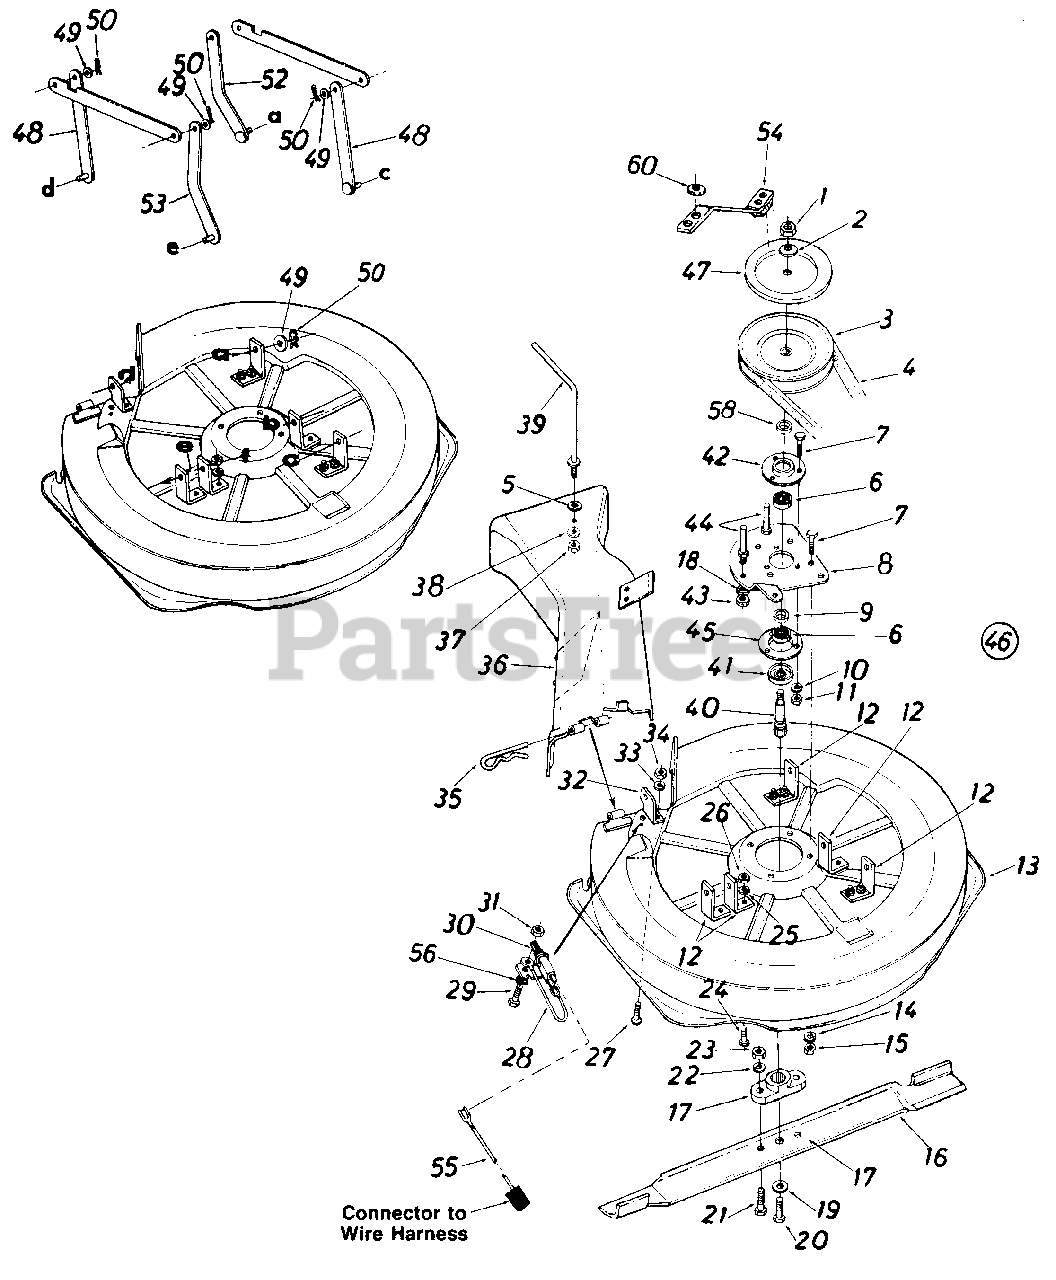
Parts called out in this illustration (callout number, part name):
1	Hex Jam Nut 5/8-18 Thd.
2	Bell-Wash. .630" I.D. x 1.25"
5	Fl-Wash. .344" I.D. x 1.12" O.D.
6	Ball Brg. .787" I.D.
7	Hex Bolt 5/16-18 x .75" Lg.
8	Spindle Mtg. Plate
9	Spacer
10	L-Wash. 5/16" I.D.
11	Hex Nut 5/16-18 Thd.
12	Hanger Bracket
15	Hex Nut 5/16-18 Thd.
16	30" High Lift Blade-R.H.
17	Blade Adapter
18	L-Wash. 3/8" I.D.
19	Bell-Wash. .39" I.D. x 1.38" O.D.
20	Hex Bolt 3/8-24 x 1.00" Lg.
21	Hex Bolt 5/16-24 x 1.00" Lg.
22	L-Wash. 5/16" I.D.
23	Hex Nut 5/16-24 Thd.
24	Hex Sems Bolt 5/16-18 x .62" Lg.
25	L-Wash. 5/16" I.D.
26	Hex Nut 5/16-18 Thd.*
27	Truss Mach. Scr. 5/16-18 x .75" Lg.
28	Electrical Wire
29	Hex Bolt 1/4-20 x .50" Lg.
30	Safety Switch
31	Hex Nut 1/4-20 Thd.
32	Angle Hanger Brkt.
33	L-Wash. 5/16" I.D.
34	Hex Nut 5/16-18 Thd.*
35	Internal Cotter Pin
36	R.D. Chute Deflector
37	Hex L-Nut 5/16-18 Thd.
38	L-Wash. .32" I.D. x .62" O.D.
39	90ø Rod 5/16-18 Thd.
40	Blade Spindle x 5.20
41	Bearing Shield
42	Open Brg. Housing 1.85" I.D.
43	Hex Jam Nut 3/8-16 Thd.
44	Stud 3/8-16 x 3.0" Lg.
45	Brg. Housing 1.85" I.D.
46	30" R.D. Deck Ass'y. Comp.
47	Brake Disc
48	Link Deck Hanger Ass'y.
49	Fl-Wash. .53" I.D. x .93" O.D.
50	Inter. Cotter Pin .50" Dia
54	Blade Brake Assy.
55	Wire Lead
56	L-Wash. 1/4" I.D.
